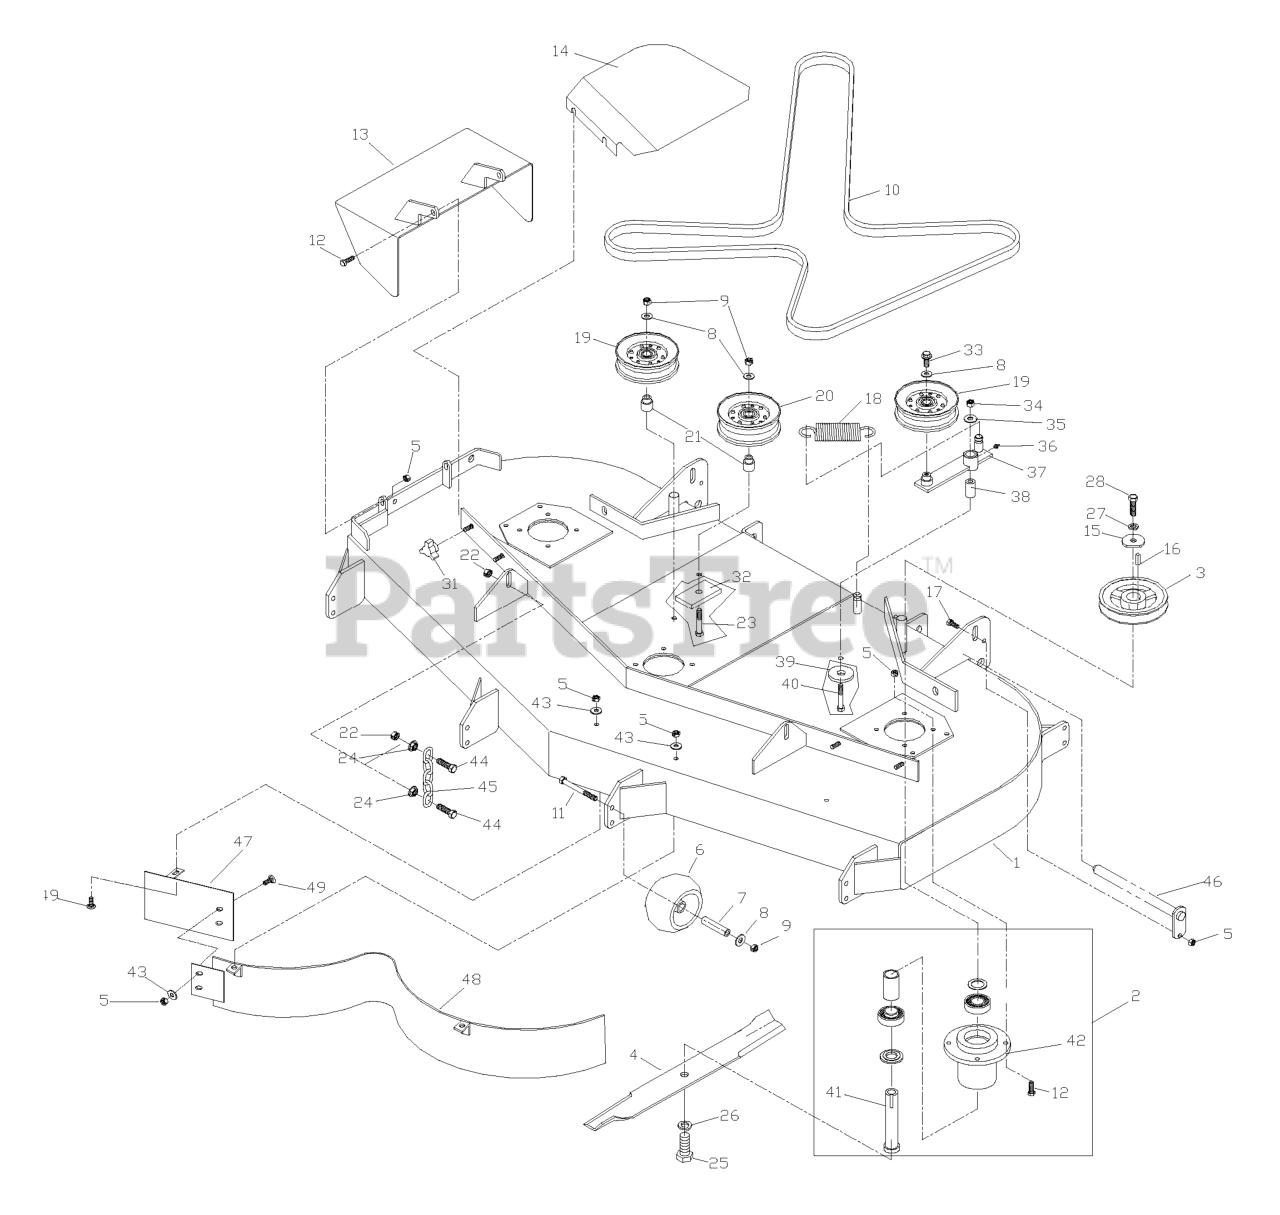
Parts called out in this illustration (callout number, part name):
1	DECK W/DECALS 52" HUS WSL
2	HOUSING KIT FOR 104403
2	BEARING KIT
3	PULLEY 52" DECK
4	BLADE OEM 18"
5	NUT 5/16C CENTERLOCK
6	ANTI-SCALP ROLLER
8	WASHER 3/8 FLAT
9	NUT 3/8C CENTERBLOCK
10	BELT, DECK
11	HCS 3/8C X 3 1/2
12	HCS 5/16C X 1
13	DISCHARGE CHUTE ORANGE
14	52 B.S.PAINTED,RT
14	52 B.S.PAINTED, LT
15	SPINDLE WASHER
16	KEY 1/4 SQ X 1 1/8
17	HCS 5/16C X 3/4
18	DECK SPRING
19	IDLER PULLEY
20	IDLER PULLEY (TALL)
21	IDLER BUSHING
22	NUT 7/16C CENTERLOCK
23	HCS 3/8C X 2 1/2
24	NUT 7/16C WHIZ
25	HCS 5/8F X 1 1/4
26	LOCKWASHER 5/8
27	WASHER 7/16 LOCK
28	HCS 7/16F X 1 1/2
31	KNOB, THREE PRONG
32	SUPPORT PLATE
33	4CS 3/8C X 1 SERRATED HEAD
34	NUT 1/2-13 HEX NYLOC ZD
35	WASHER 1/2 FLAT
36	ZERK
38	PIVOT BUSHING
39	WASHER, SUPPORT
40	HCS 1/2C X 3 1/4
42	HOUSING, DIE CAST
43	WASHER 5/16 FLAT
44	HCS 7/16C X 1 1/2
45	LIFT CHAIN
47	CENTER BAFFLE - 52"
48	MAIN BAFFLE 52"
49	CARRIAGE BOLT 5/16C X 5/8"
